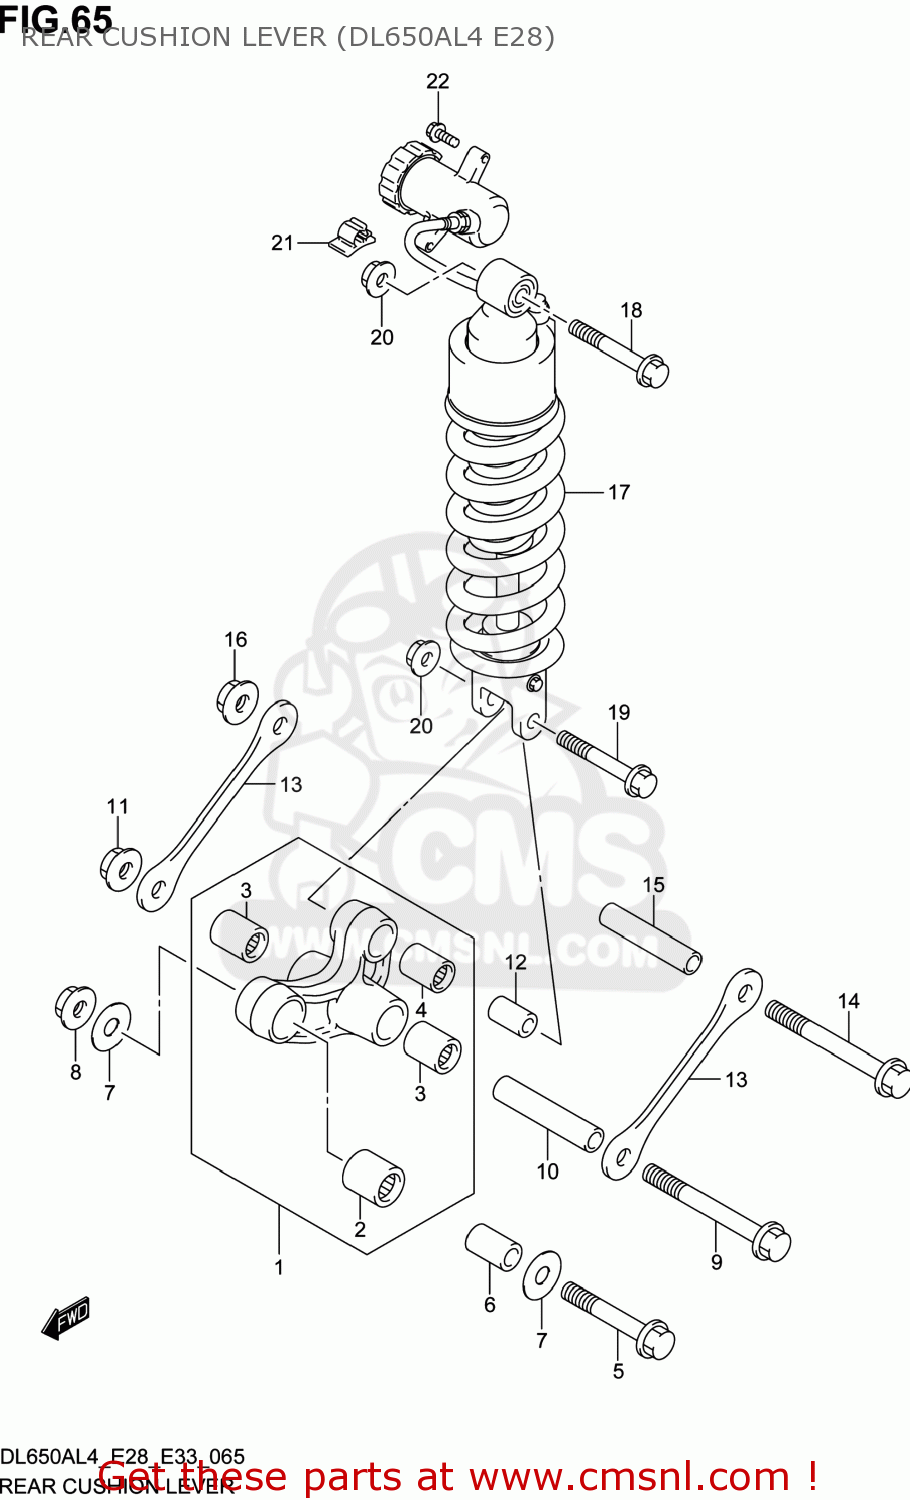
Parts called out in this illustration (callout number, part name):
1	LEVER SET,RR CUSHION
2	BEARING(20X27X30)
3	BEARING(17X24X25)
4	BEARING(17X24X26)
5	BOLT,RR CUSHION LEVER FR
6	SPACER,RR CUSHION LEVER FR
7	WASHER(12X34X1)
8	NUT
9	BOLT,RR CUSHION ROD
10	SPACER(12X17X85)
11	NUT
12	SPACER,RR CUSHION LEVER
13	ROD,RR CUSHION LEVER
14	BOLT,RR CUSHION ROD
15	SPACER(12X17X85)
16	NUT
17	ABSORBER ASSY,RR SHOCK
18	BOLT(10X70)
19	BOLT(10X55)
20	NUT
21	CLAMP
22	BOLT
